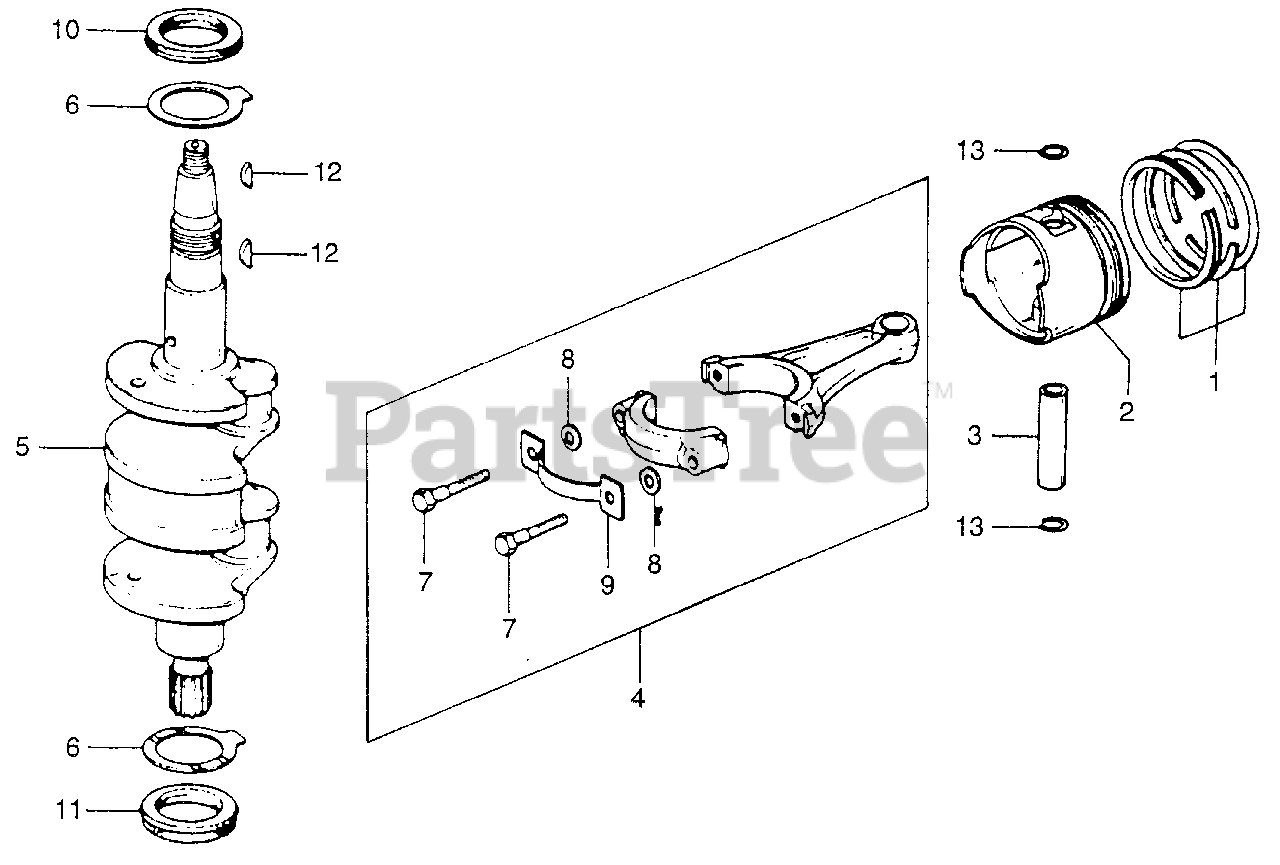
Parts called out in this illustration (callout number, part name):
1	RING SET, PISTON (STD)
3	PIN, PISTON
4	ROD ASSY., CONNECTING
5	CRANKSHAFT, R.
6	BEARING, CRANKSHAFT THRUST
7	BOLT, CONNECTING ROD
8	WASHER (6MM)
9	WASHER, LOCK
10	OIL SEAL A (30X42X7)
11	OIL SEAL B (30X42X7)
12	KEY, WOODRUFF (16X15)
13	CLIP, PISTON PIN (14MM)
